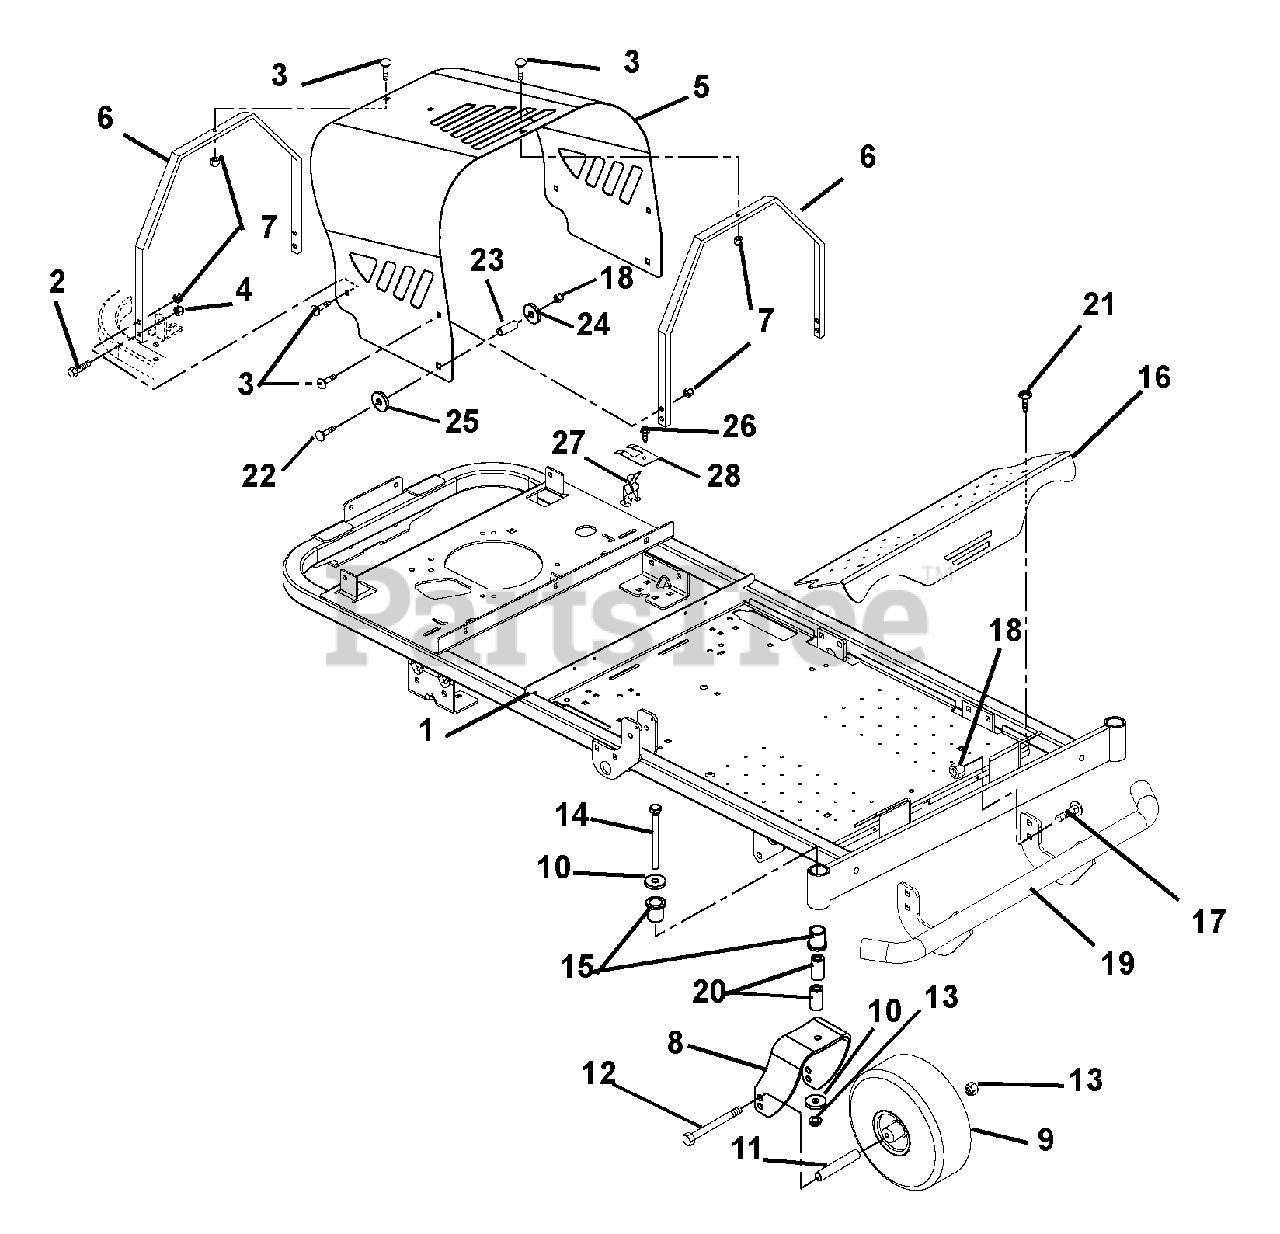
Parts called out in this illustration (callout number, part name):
1	Weldment, Frame (065)
2	Bolt, Shoulder .375-16 x .135
3	Bolt, Round Head Square Neck .31-18 x .62
4	Nut, Locking Top Flange .38-16
5	Engine Hood
6	Brace, Hood
7	Nut, Locking Top Flange .31-18
8	Fork, Caster
9	Assembly, Tire 4 x 11- 2 Ply
10	Washer, Flat Steel .511 x 1.441 x .125
11	Spacer, Wheel
12	Bolt, Hex .50-13 x 6.50 Grade 5
13	Nut, Locking Top Flange .50-13
14	Bolt, Hex .50-13 x 5.00 Grade 5
15	Bushing, Flange 1.00 x 1.25 x 1.50 x 1.50
16	Foot Rest
17	Bolt, Round Head Square Neck .38-16 x 1.00 Grade 5
18	Nut, .38-16 Flange Nyloc
19	Bumper, Zoom
20	Spacer, Caster
21	Screw, Tap .31-18 x .50
22	Bolt, Round Head Square Neck .38-16 x 2.50 Grade 5
23	Hood Snap
24	Washer, Flat Steel .375 x 1.125 x .065
25	Washer, Flat Steel .531 x 1.06 x .095
26	Screw, Tap .25-20 x .50
27	Hood Clip
28	Bracket, Hood Clip
